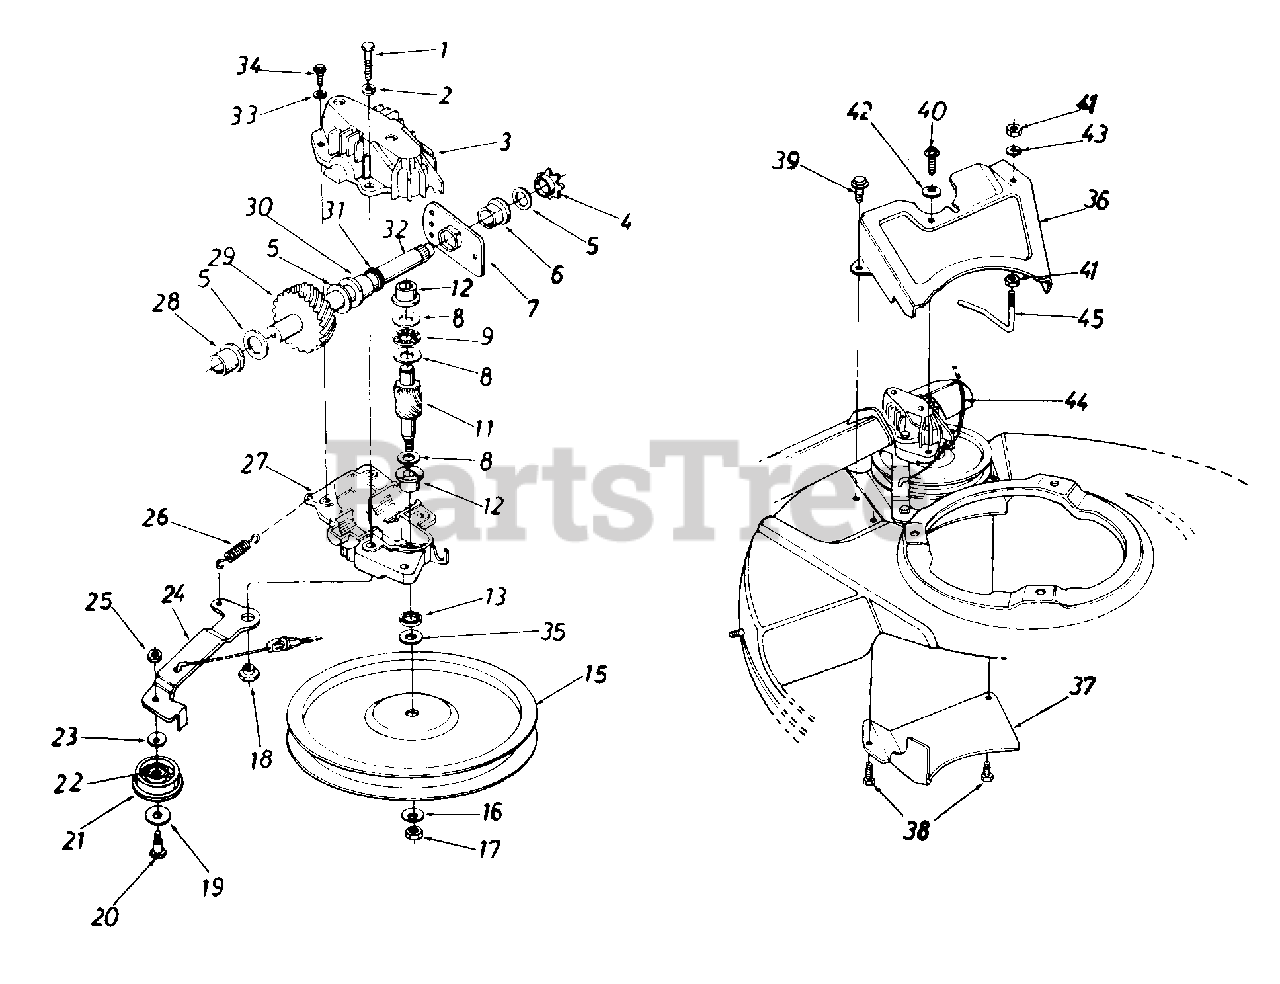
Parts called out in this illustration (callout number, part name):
1	Hex Bolt 1/4-20 x 1.25" Lg.* w/ Patch
2	L-Wash. 1/4" I.D.*
3	Upper Hsg. Half
4	#48 Sprocket 7 Tooth x 1/2 Pitch
5	Fl-Wash. 518" I.D. x .030
6	Hex Flange Brg. .631" I.D.
8	Thrust Wash. .382" I.D. x .70" O.D.
9	Thrust Bearing .375" I.D. x .812" O.D.
11	11 Tooth Helical Gear
12	Flange Bearing
13	Oil Seal
15	Fl-Pulley 5.06" I.D.
16	Bell-Wash. .265" I.D. x .75"
17	Hex Nut 1/4-28 L.H. Thd.
18	Shld. Spacer .375" Dia. x .170
19	Fl-Wash. .390" I.D. x 1.0"
20	Shld. Bolt .375" Dia. x .40"
21	Fl-Idler Plastic 1.50" Dia.
22	Needle Brg. .375" x .31"
23	Bell-Wash. .265" I.D. x .75"
24	Idler Brk't. Ass'y.
25	Hex Patch L-Nut 1/4-28 Thd.
26	Extension Spring 1.12" Lg.
27	Lower Hsg. Half
28	Flange Bearing .56 Dia.
29	33 Tooth Helical Gear
30	Flange Bearing .629 Dia.
31	Oil Seal .625 Dia.
32	Gear Sprocket Shaft
33	L-Wash. #10 I.D.
34	Hex B-Tap Scr. #10 x .62"
35	Hex Washer .26" x .88"
39	Hex AB-Tap Scr. 1/4 x .50" Lg.
40	Hex B-Tap Scr. 1/4 x .62" Lg.
41	Hex Nut 1/4-20 Thd.*
42	Bell-Wash. .265" I.D. x .75"
43	L-Wash. 1/4" I.D.*
44	S.P. Cable-48" Lg.
45	S.P. Belt Guard
